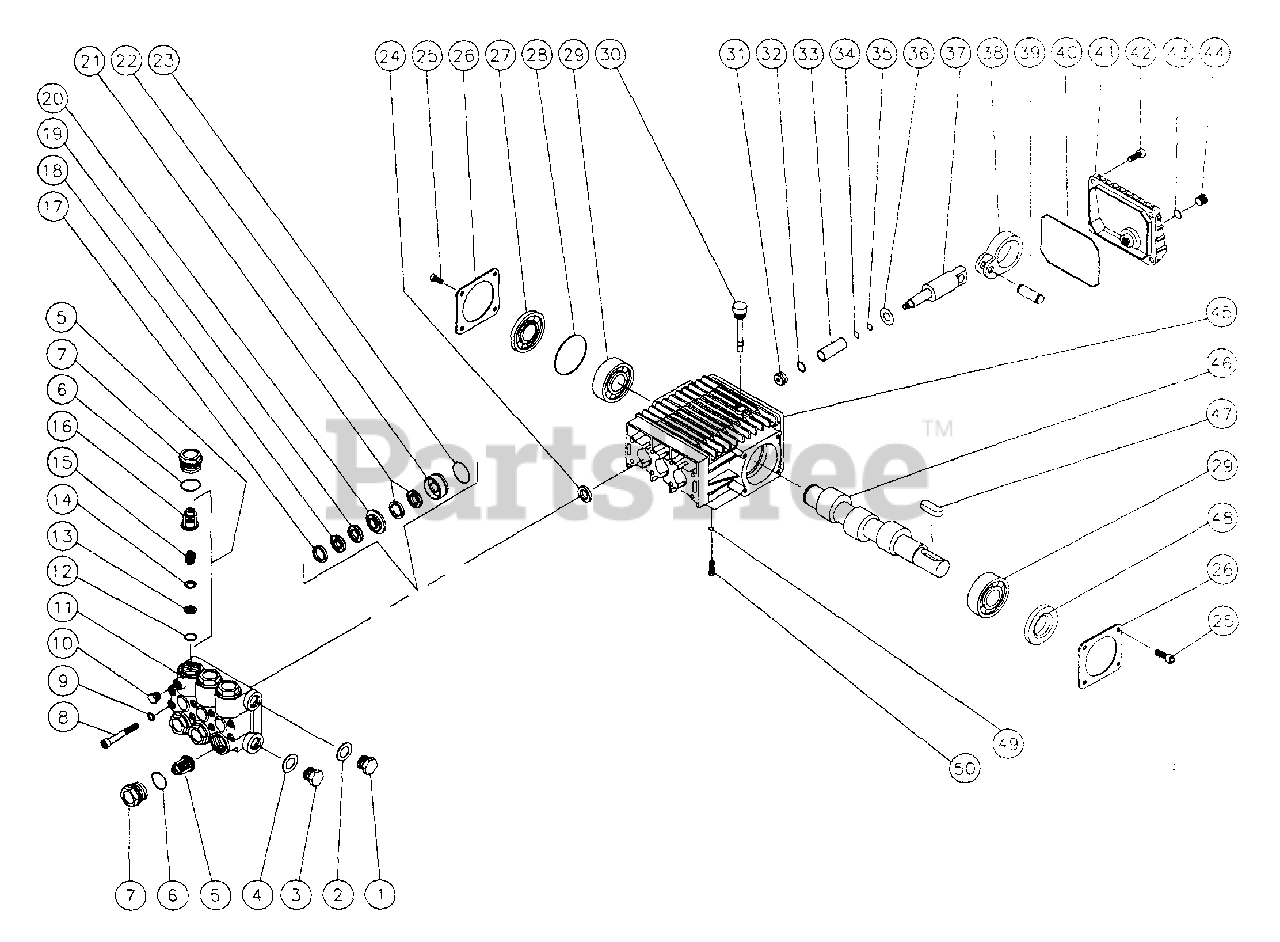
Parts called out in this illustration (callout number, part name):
1	Hex Plug
3	Hex Plug
5	Valve Assy
7	Valve Plug
8	Bolt
9	Lockwasher
10	Hex Plug
11	Pump Manifold - Brass 18mm
12	O-ring
13	Valve Seat
14	Valve Plate
15	Valve Spring
16	Valve Cage
17	Head Ring
18	V-Packing
19	Stop Ring Packing
20	Intermediate Ring
21	Pressure Seal
22	Packing Retainer
24	Oil Seal
25	Bolt
26	Retainer/Oil Level/Spacer
27	Oil Level Indicator/Spacer
29	Ball Bearing
30	Oil Dipstick
31	Nut
35	Back-up Ring
36	Flinger Washer
37	Piston Guide
38	Connecting Rod
39	Pin for Connecting Rod
41	Crankcase cover
42	Bolt
44	Hex Plug
45	Crankcase
46	Crankcase Shaft
48	Oil Seal
49	Lockwasher
50	Bolt
